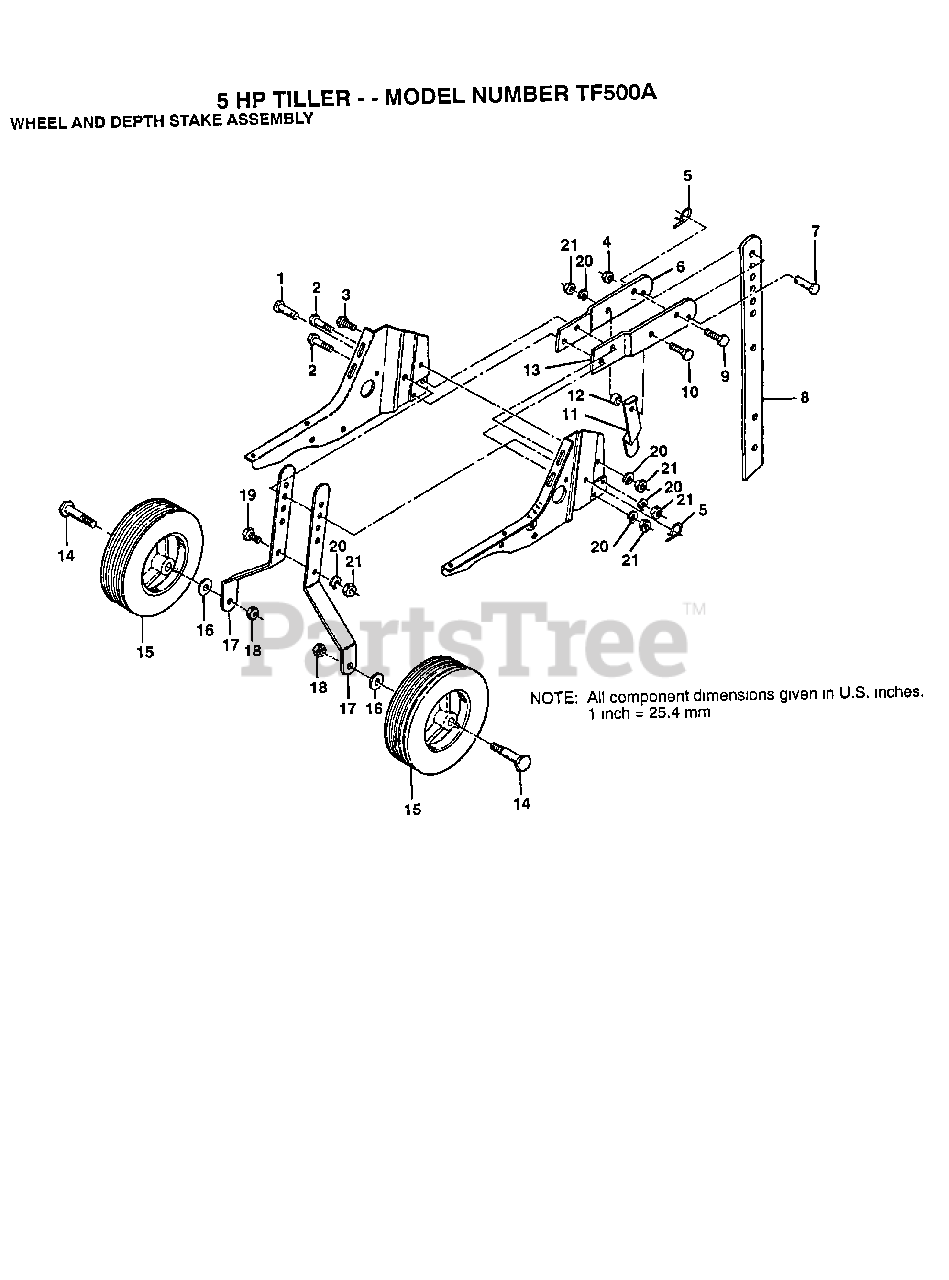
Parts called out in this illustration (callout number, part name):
1	DRILLED RIVET RT
3	BOLT
4	GRIPCO NUT
5	SPRING.RETAINER
9	BOLT.3/8-24X1-1/2
10	BOLT.HEX.5/16-1.5
11	STAKE SPRING TI
12	WASHER
14	BOLT SHOULDER
16	WASHER
20	LOCKWASHER
21	NUT.HEX.5/16-18
